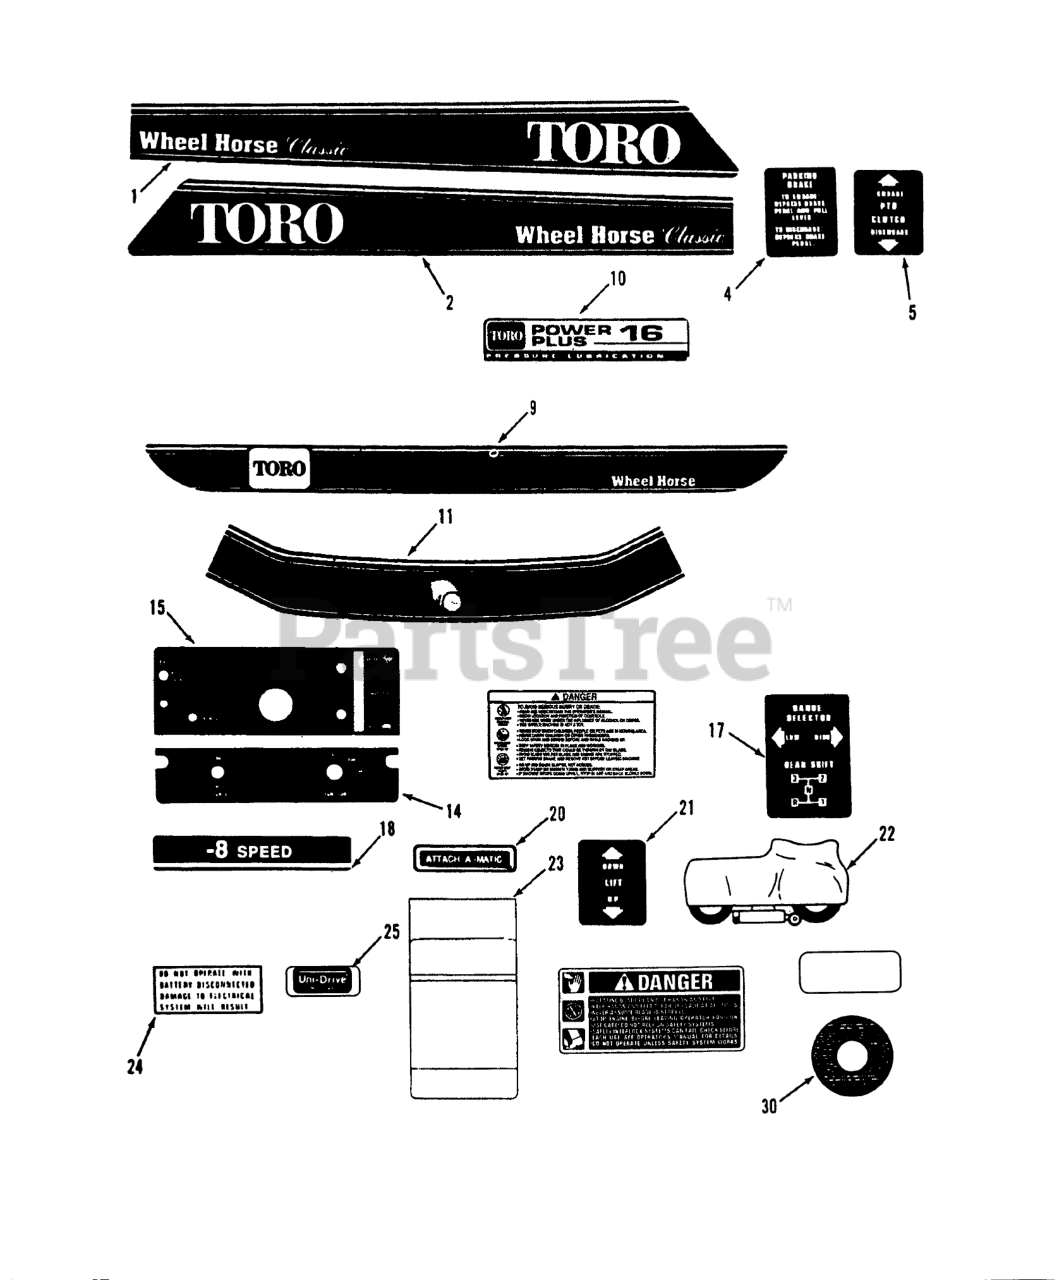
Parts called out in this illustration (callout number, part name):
1	DECAL-HOOD 416-8 R H
2	DECAL-HOOD 416-8 L H
4	DECAL-PARKING, BRAKE
5	DECAL PTO CLUTCH
9	DECAL-FENDER
10	DECAL-PWR PLUS 16 PL
11	DECAL-FRONT HOOD
14	Decal-Switch Plate
15	DECAL-LOWER DASH
17	DECAL-SHIFT PATTERN
18	DECAL-MODEL 8-SPEED
20	Decal-Attac-O-Matic
21	DECAL-LIFT
22	Vinyl Tractor Cover
23	MAINTENANCE-DECAL
24	DECAL ELECT SYSTEM
25	Decal-Unidrive
